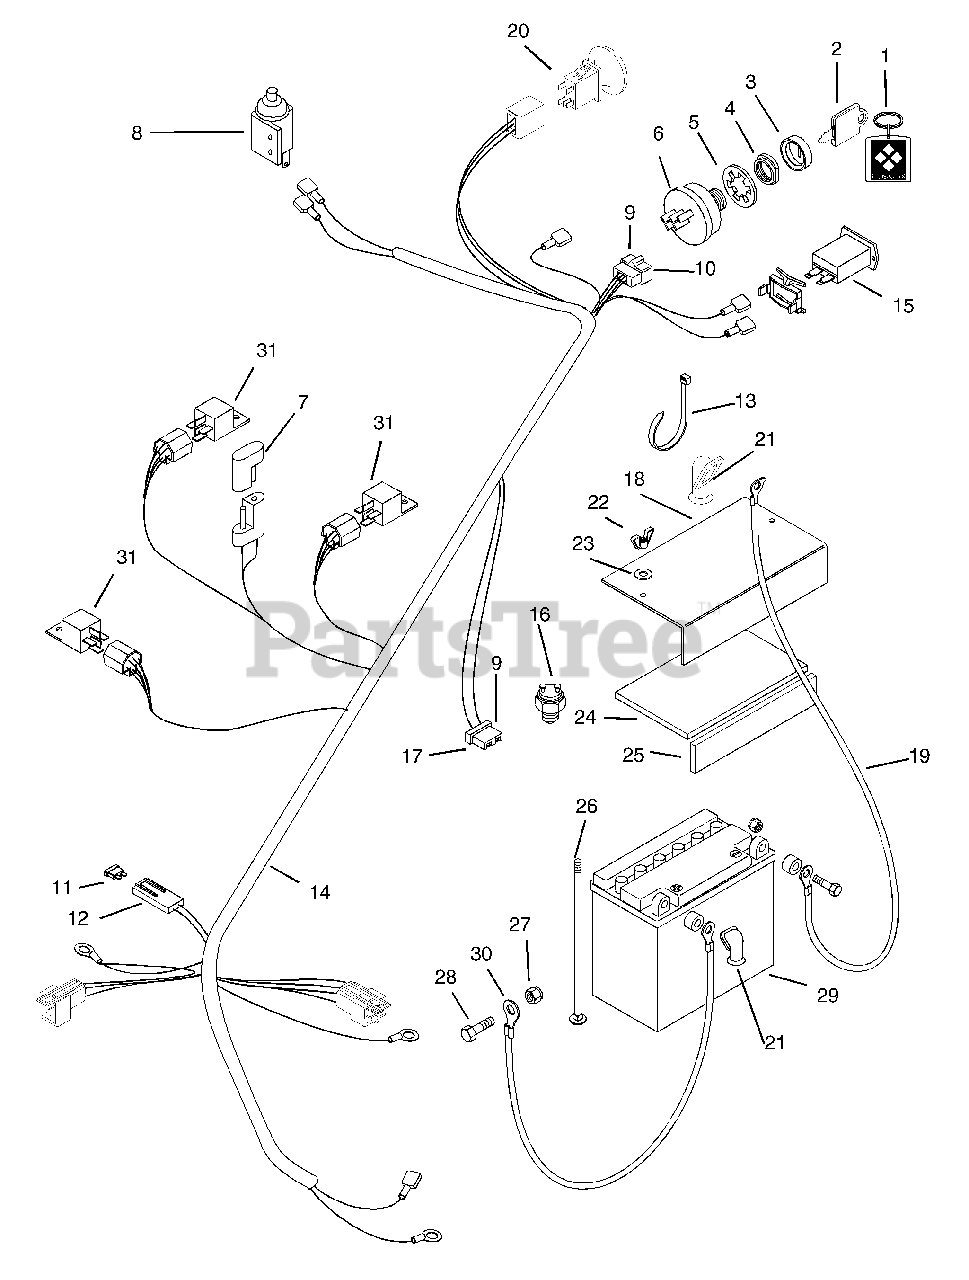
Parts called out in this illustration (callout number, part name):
1	Key Chain
2	Ignition Switch Key
3	Cap-Ignition Switch
4	Nut-Panel .625-32
5	Washer-Lock-Internal .625 x .045
6	Key Switch Assembly
7	Molded diode Plug-Clear 1 AMP
8	Single Pole N.O. with Cover
9	Terminal
10	Connector
11	Fuse-30 AMP
12	Terminal-For 10-12 Gauge Wire
13	Tie-Wrap-Black
14	Wire Harness-Pro 200 Robin
15	Hour Meter
16	Switch-Neutral Start (N.C.)
17	Connector-2-Wire-Switch
18	Cover-Battery
19	Cable Battery
20	Switch-clutch with Retainer
21	Boot-Insulator
22	Nut-Locking-Wing
23	Washer-flat-steel .281 x .625 x .065
24	Pad-Battery
25	Pad-Battery
26	Bolt-Round Head Square Neck .25-20 x 7.00 Grade 2
27	Nut-Locking-Center .31-18
28	Bolt-Hex .31-18 x 1.00 Grade 5
29	Battery-12 Volt
30	Cable-Negative Battery
31	Relay
